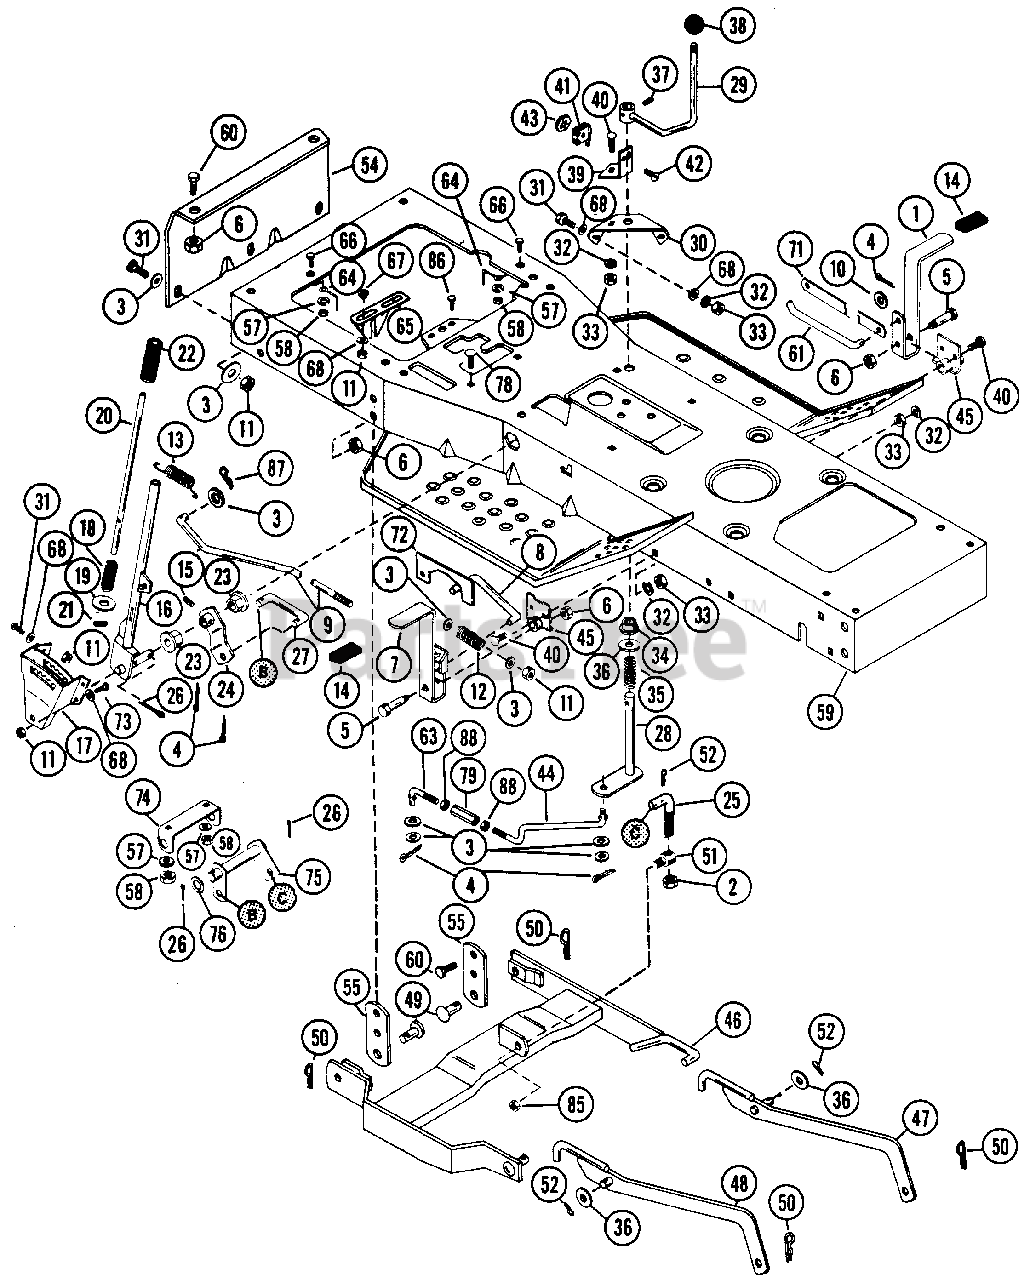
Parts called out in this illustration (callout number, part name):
1	CLUTCH PEDAL
2	NUT, JAM 1/2-13 HEX
3	WASHER, FLAT .406X.812X.065
4	PIN, COTTER .125X1.00
5	SHOULDER BOLT
6	NUT, LOCK 3/8-16
7	BRAKE PEDAL
8	PARKING BRAKE ROD
9	BRAKE ROD
10	WASHER, FLAT .438X1.000X.083
11	NUT, LOCK 5/16-18
12	BRAKE SPRING
13	EXTENSION SPRING
14	PEDAL COVER
15	PIN, GROOVE 1/4X1-1/4
16	LIFT HANDLE
17	LIFT QUADRANT
18	SPRING
19	WASHER, FLAT .56X1.87X.109
20	PLUNGER ROD
21	PIN, SPRING .250X1.750
22	GRIP
23	FLANGE BUSHING
24	LIFT ARM
25	ADJUSTMENT LINK
26	PIN, COTTER .125X1.500
27	LIFT LINK
28	PTO LEVER
29	PTO HANDLE
30	BRACKET
31	BOLT, HEX 5/16-18X.75
32	WASHER, LOCK 3/8 SP HEAVY
33	NUT, HEX 5/16-18
34	FLANGE BUSHING
35	COMPRESSION SPRING
36	WASHER, FLAT .500X1.250X.083
37	PIN, SPRING .187X1.250
38	SHIFT BALL
39	SWITCH BRACKET
40	BOLT, CARRIAGE 5/16-18X.75
41	SWITCH, INTERLOCK - PTO
42	SCREW, MACHINE 10-24X.625
43	NUT, KEPS 10-24
44	IDLER LINK
45	PEDAL PIVOT
46	REAR HANGER
47	FRONT HANGER ARM - RIGHT
48	FRONT HANGER ARM - LEFT
49	CLEVIS PIN
50	HAIR PIN, INTERNAL .094
51	ROD END
52	HAIR PIN, INTERNAL
54	DRAW BAR
55	HANGER BRACKET
57	WASHER, LOCK 3/8 REG.
58	NUT, HEX 3/8-16
60	BOLT, HEX 3/8-16X.75
61	CLUTCH ROD
63	IDLER ADJUSTOR LINK
64	BELT FINGER
65	CAM ACTUATOR
66	BOLT, HEX 3/8-16X1.00
67	SPACER
68	WASHER, FLAT .312X.734X.065
71	LINK
72	CAM
73	BOLT, HEX 5/16-18X1.25
74	CENTER LIFT BRACKET
75	CENTER LIFT LEVER
76	WASHER, FLAT .938X1.750X.134
78	BOLT, CARRIAGE 3/8-16X.75
79	COUPLING NUT 3/8-16
85	NUT, LOCK 1/2-13
86	BOLT, HEX 5/16-18X.875
87	PIN, HAIR INT. 3/32X1.187
88	NUT, JAM 3/8-16 HEX
